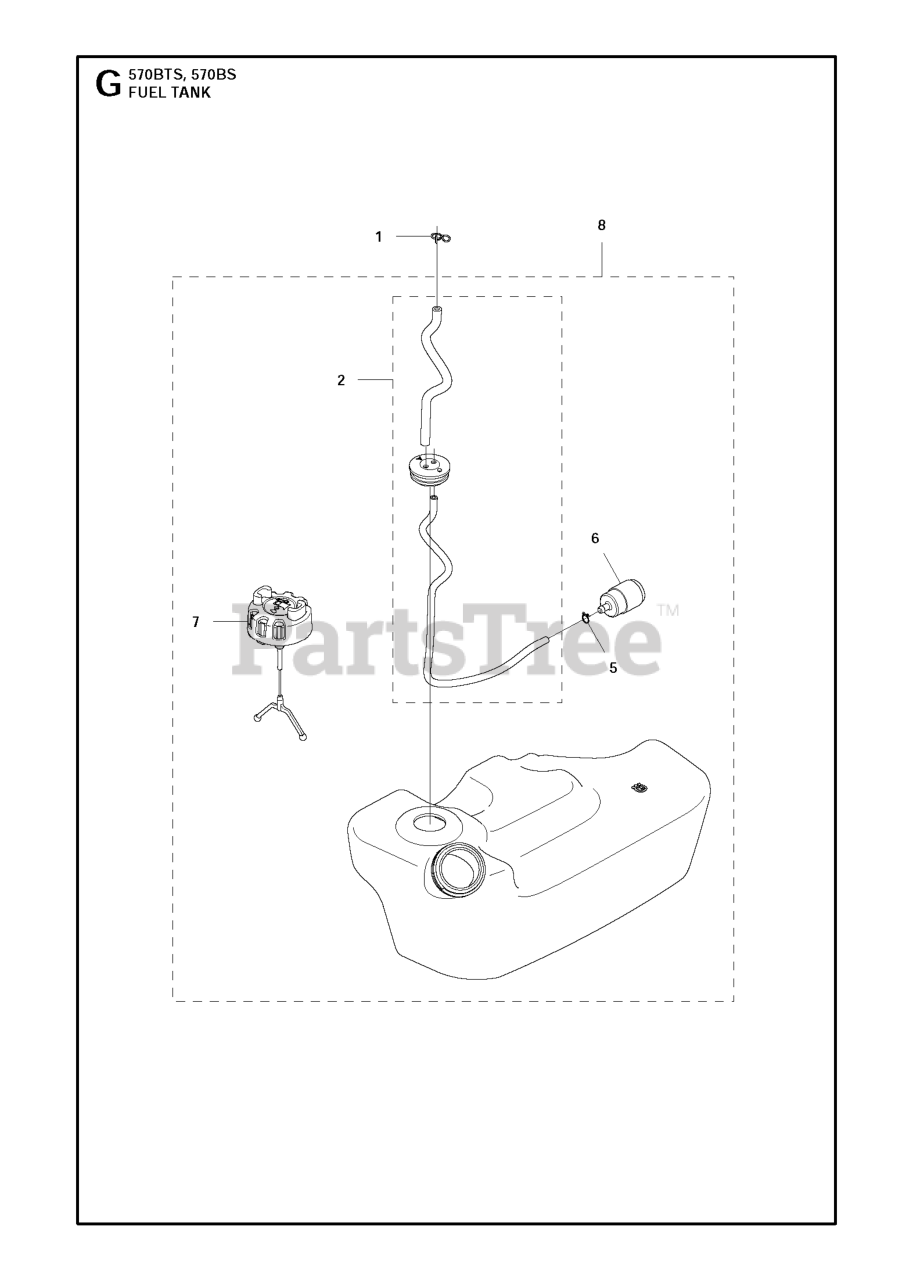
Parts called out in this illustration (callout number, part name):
2	PIPE ASSY
6	FILTER ASSY
7	FUEL CAP ASSY
8	FUEL TANK ASSY
8	ASSY TANK EVP
